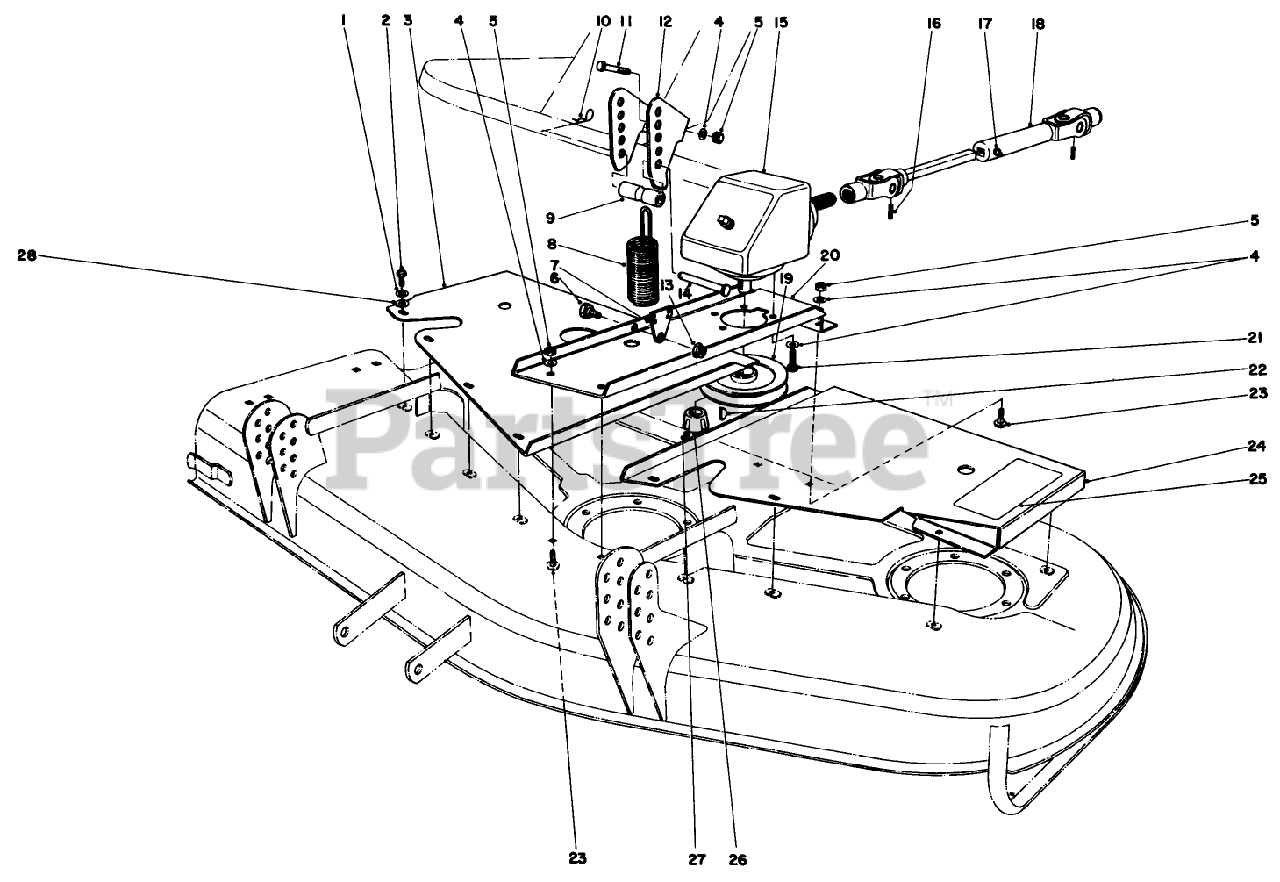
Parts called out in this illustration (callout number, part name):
1	SCREW-HH
3	RH COVER WA *R
4	WASHER-LOCK
5	NUT-HEX
6	BOLT-SHOULDER
9	SPACER
10	PIN-HAIR
11	SCREW-HH
12	SPRING BRACKET *R
13	NUT-HHF, WHIZ
14	PIN-CLEVIS
16	PIN-ROLL
17	FITTING-GREASE
18	UNIVERSAL JOINT
21	SCREW-HSH
22	KEY-WOODRUFF
23	SCREW-CARR
24	LH COVER WA *R
26	BUSHING-LOCK, TAPER
27	SCREW-SET, HSH
28	WASHER-FLAT
